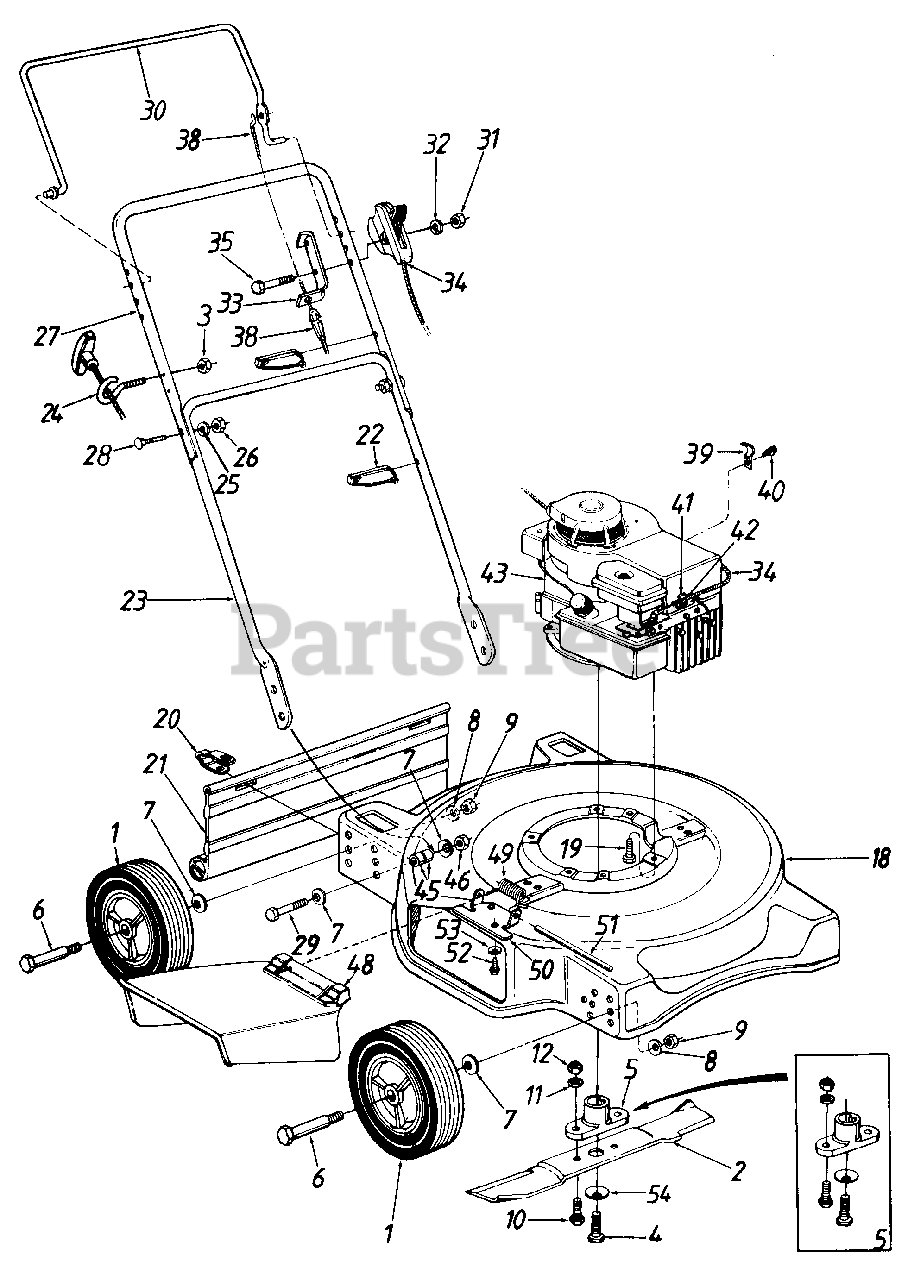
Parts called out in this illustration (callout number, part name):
1	Wheel Ass'y. Complete
2	20" Blade
3	Hex L-Nut 1/4-20 Thd.
4	Hex Bolt 3/8-24 x 1.5" Lg.
5	Blade Adapter Kit (Keyed)
6	Axle Bolt Rib Tread (Plastic Rim)
7	Bell-Wash. .380" I.D. x .88"
8	Bell-Wash. .39" I.D. x 1.13"
9	Hex Nut 3/8-16 Thd.
10	Hex Bolt 3/8-24 x 1" Lg.
11	L-Wash. 3/8" I.D.
12	Hex Nut 3/8-24 Thd.
18	20" Deck Ass'y.
19	Hex Wash. Hd. Scr. 3/8-16 x 1 " Lg.
20	Hinge Clip
21	Rear Flap 16.75" Lg.
22	Cable Tie
23	Lower Handle
24	Rope Guide Bolt
25	L-Wash. 5/16" I.D.
26	Hex Nut 5/16-18 Thd.
27	Upper Handle
28	Curved Carriage Bolt 5/16-18 x 1.38" Lg.
29	Hex Bolt 3/8-24 x 1.5" Lg.
30	Control Handle
31	Hex Nut 1/4-20 Thd.
32	Spr. Wash. .265" I.D. x .562"
33	Cable Mounting Bracket
34	Throttle Control Ass'y. Comp.
35	Hex Bolt 1/4-20 x 1.875" Lg.
38	Control Cable 36"
39	Casing Clamp
40	Hex B-Tap Scr. #10 x .38" Lg.
41	Casing Clamp
42	Hex Wash. Hd. AB-Tap Scr. #8 x .50" Lg.
43	Engine
45	Spacer
46	Hex L-Nut 3/8-24 Thd.
48	Chute Deflector Ass'y.
49	Torsion Spring
50	Adapter Plate
51	Hinge Pin
52	Hex Self-Tap Scr. 1/4-20 x .5"
53	Bell-Wash. 1/4" I.D.
54	Bell-Wash..39" I.D.
